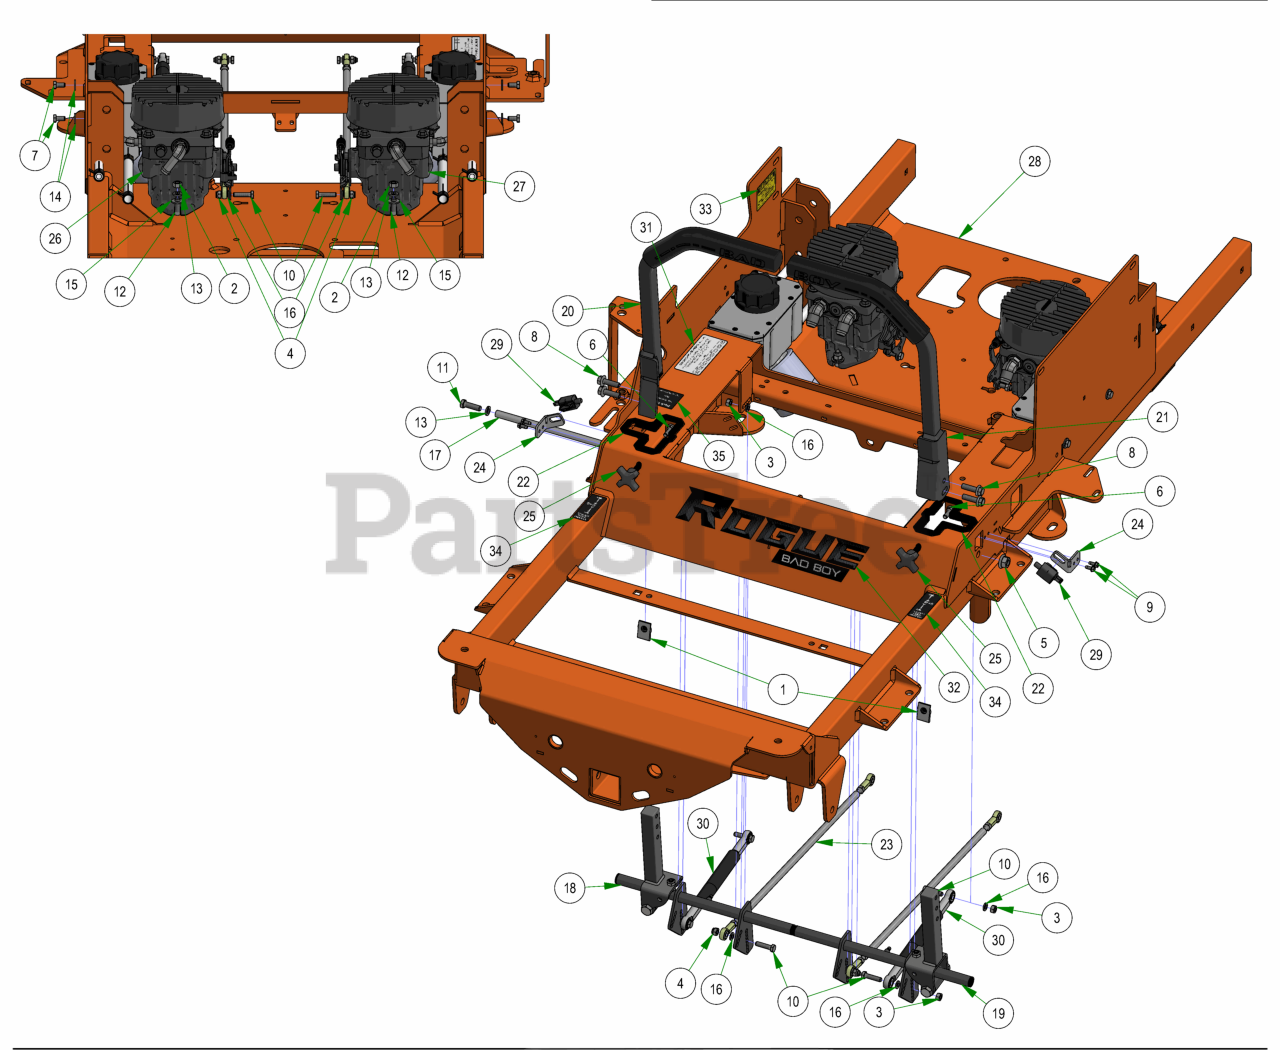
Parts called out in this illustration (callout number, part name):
1	Extruded Nut 3/8"-16 3/4" Hole Center With Patch
2	3/8-16 HEX NUT ZINC
3	5/16-18 HEX NUT ZINC
4	5/16-18 NYL INS L/N ZC
5	1/2-13 NYLON INSERT FLANGE LOCKNUT ZINC
6	5/16-18 HEX SERRATED FLANGE NUT HARD/ZINC
7	5/16-18 x 5/8 Hex Bolt
8	3/8-16 X 1 1/4 HEX WASHER UNSLOT MACHINE SCREW ZINC GR5
9	12-24 X 1/2 HEX WASHER UNLSOT F TCS ZINC
10	5/16-18 X 1-1/4 HEX C/S (GR.5) ZC
11	3/8-16 X 1-1/4 HEX CAP SCREW (GR.5) ZINC
12	3/8-16 X 1-1/2 HEX CAP SCREW (GR.5) ZINC
13	3/8 SPLIT LOCKWASHER ZINC
14	1/4 USS FLAT WASHER (3/4 OD) ZINC
15	5/16 USS FLAT WASHER (7/8 OD) ZINC
16	5/16 SPLIT LOCKWASHER ZINC
17	2019 Steering Actuator Rod
18	R Series Square Drive Arm Actuator RH Assembly
19	R Series Square Drive Arm Actuator LH Assembly
20	R Series Square Drive Arm RH Assembly
21	R Series Square Drive Arm LH Assembly
22	Snap-in Drive Arm Bushing
23	2019 Outlaw Gen2 XP Push Rod Assembly
24	Push In Arm Safety Switch R Series Bracket
25	Speed Limiting Knob 3/8-16X 3"
26	2021 LH ROGUE HYDRO TANK LINE ASSY
27	2021 RH ROGUE HYDRO TANK LINE ASSY
28	2023 Rogue Frame - Painted
29	Rail Mount Safety Switch
30	2019 SROID Damper With Spherical Rod Ends
31	2024 EPA Build Date Punch Decal
32	Rogue back Plate & Front Decal
33	Hydraulic Decal
34	2018 LH/RH Steering Control Decal Roll
35	2019 Deck Release Decal
